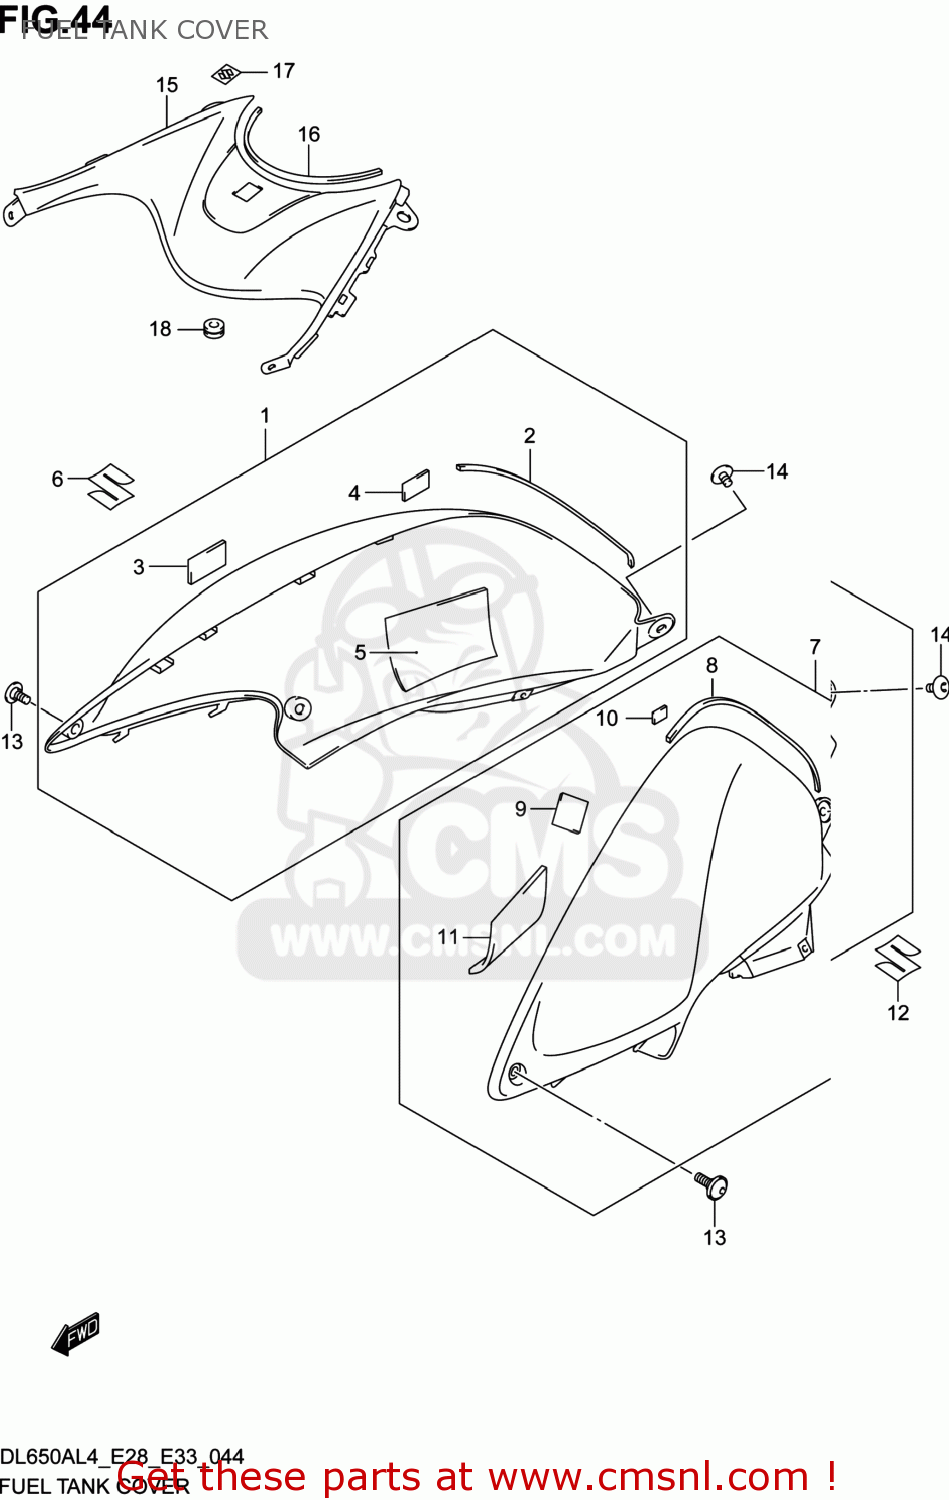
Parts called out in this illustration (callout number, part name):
1	COVER,FUEL TANK SIDE,R(RED)
2	CUSHION,FUEL TANK COVER
3	FASTENER
4	FASTENER
5	CUSHION,FUEL TANK
6	EMBLEM, S
7	COVER,FUEL TANK SIDE,L(RED)
8	CUSHION,FUEL TANK COVER
9	FASTENER
10	FASTENER
11	CUSHION,FUEL TANK
12	EMBLEM, S
13	SCREW(5X13)
14	SCREW,FUEL TANK COVER
15	COVER,FUEL TANK FR
16	CUSHION,FUEL TANK FR COVER
17	EMBLEM,"S"
18	CUSHION
